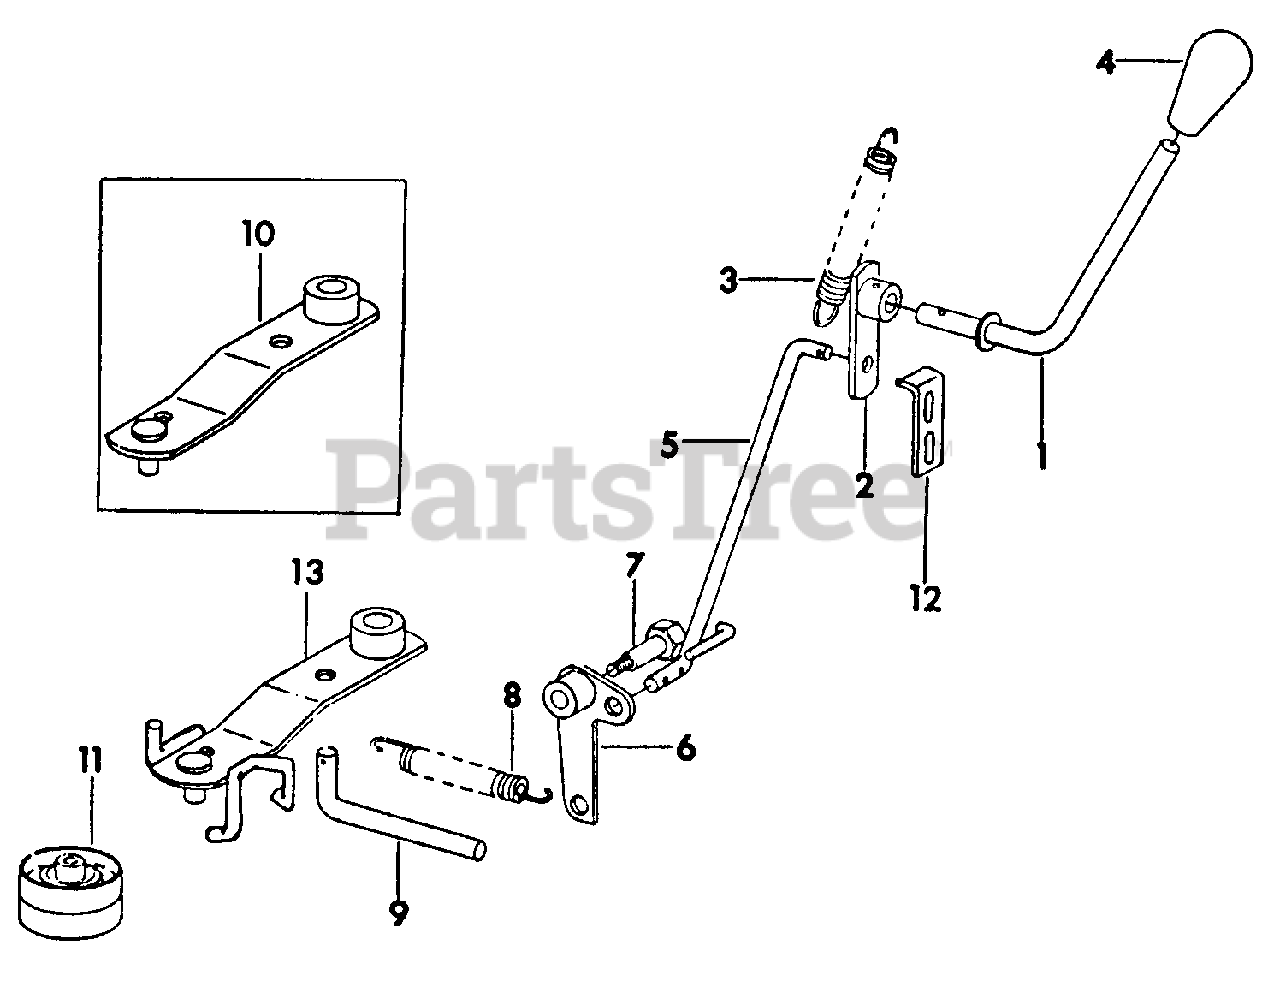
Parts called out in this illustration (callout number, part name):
1	Arm Assy, Shifter
2	Lever Assy, Shifter Arm
3	Spring, Extension
4	Grip, Shifter Arm
5	Rod Assy, Mower Clutch
6	Actuator Assy, IPTO
7	Bolt, Shoulder IPTO
8	Spring, IPTO
9	Rod, IPTO Return
10	Not used in this application
11	Pulley, Mower Shift Idler
12	Stop, IPTO Control
13	Arm Assy, IPTO Idler
